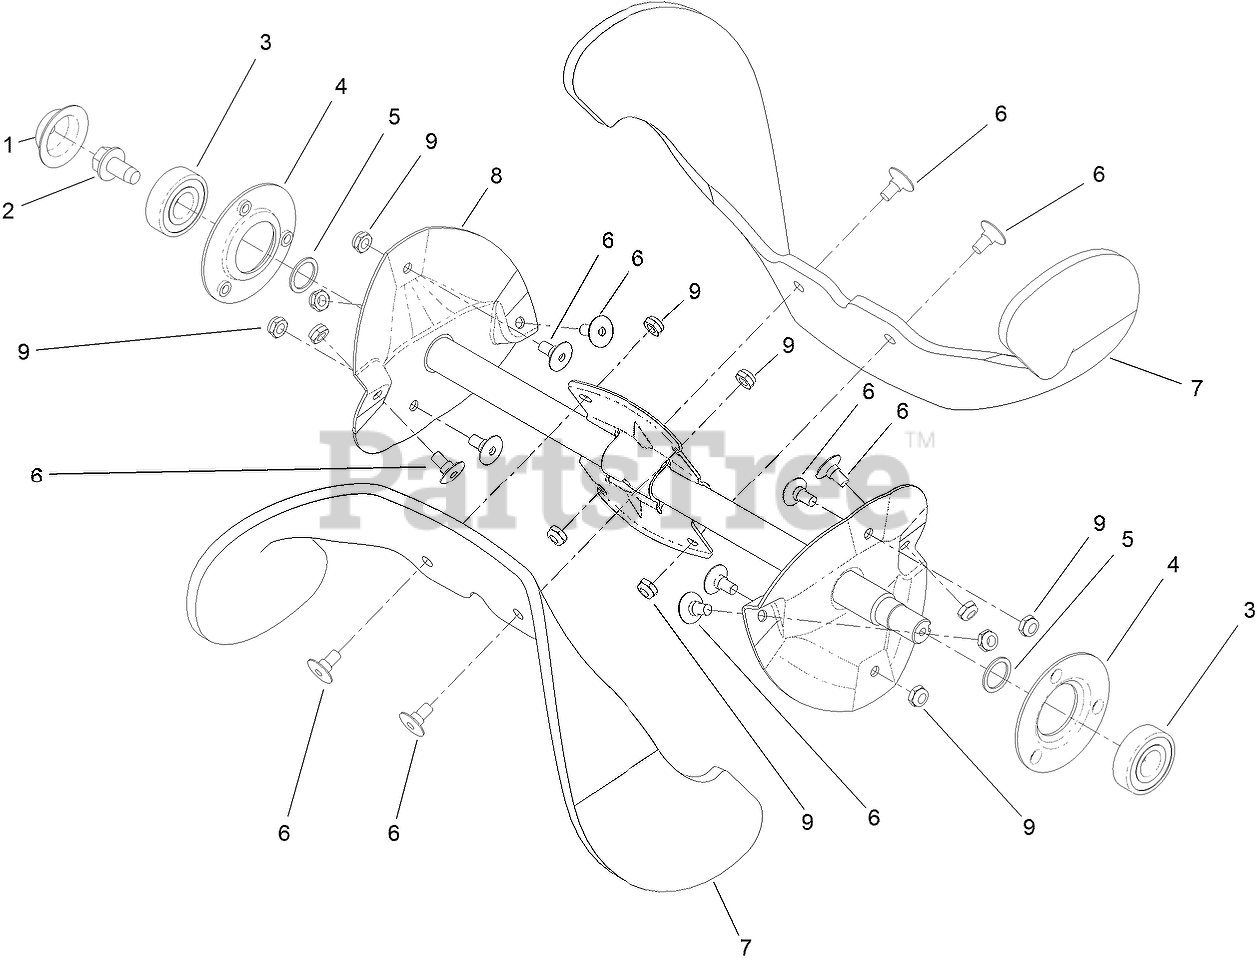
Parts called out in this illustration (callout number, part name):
1	CAP-SIDEPLATE, RH
2	SCREW-HWH
3	BEARING-BALL
4	FLANGE-BEARING
5	WASHER-THRUST
6	SCREW-COUNTERSUNK, OVAL
7	BLADE-ROTOR
8	ROTOR ASM
9	NUT-HEX
